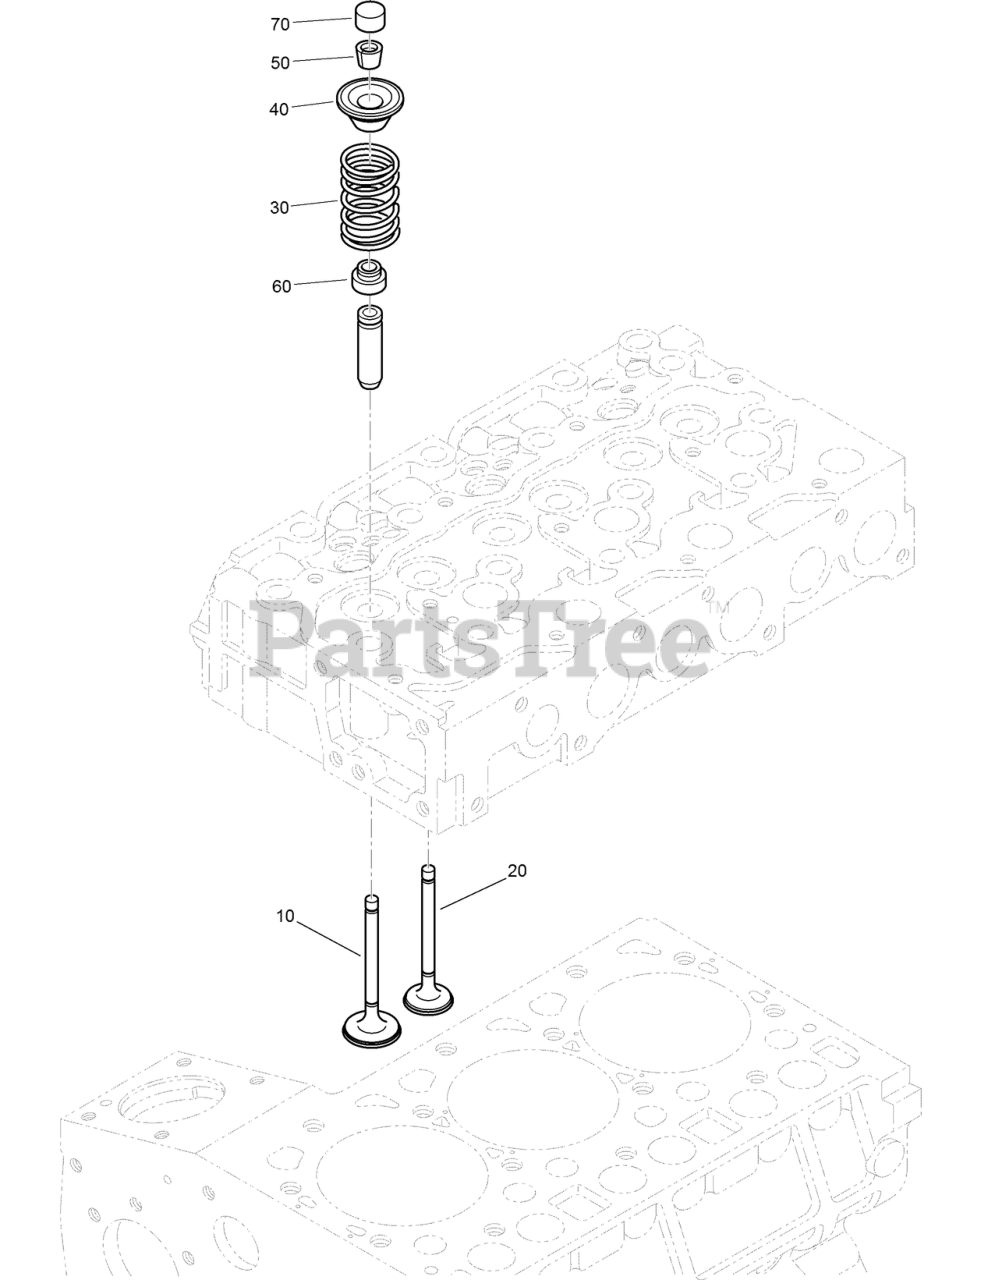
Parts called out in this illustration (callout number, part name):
10	VALVE-INLET
20	VALVE-EXHAUST
30	SPRING-VALVE
40	RETAINER-SPRING, VALVE
50	COLLET-VALVE, SPRING
60	SEAL-STEM, VALVE
70	CAP-VALVE
